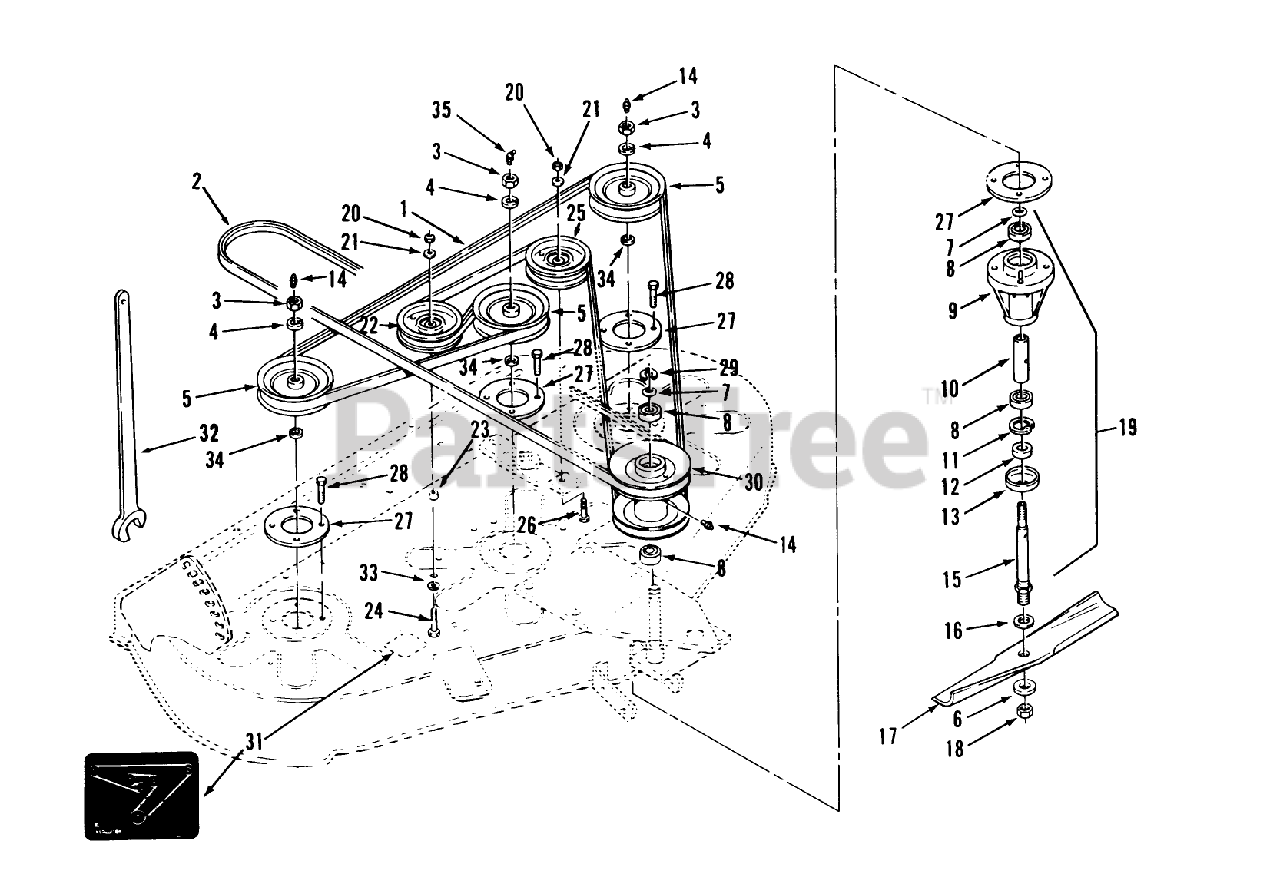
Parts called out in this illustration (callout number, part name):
1	V-BELT
2	V-BELT
3	NUT-JAM
4	WASHER-LOCK
5	PULLEY-SPINDLE
6	WASHER-FLAT
7	O RING
8	BEARING-BALL
9	HOUSING-SPINDLE
11	Ring-Snap
12	SPACER-BLADE
13	CUP-SPINDLE
14	FITTING-GREASE
15	SHAFT-SPINDLE
16	Washer
17	BLADE KIT
18	NUT-JAM
19	Spindle Assembly (Incl. ref. #7-15)
20	NUT-LOCK, NI
21	WASHER-FLAT
22	Pulley-Idler
23	SPACER
24	SCREW-CARR
25	PULLEY-FLAT IDLER
26	SCREW-HH
27	SPACER-SPINDLE
28	SCREW-HH
29	RETAINING RING
30	PULLEY-COUNTER SHAFT
31	DECAL-BELT INSTALL
32	Spindle Wrench
34	Washer
35	FITTING-GREASE
